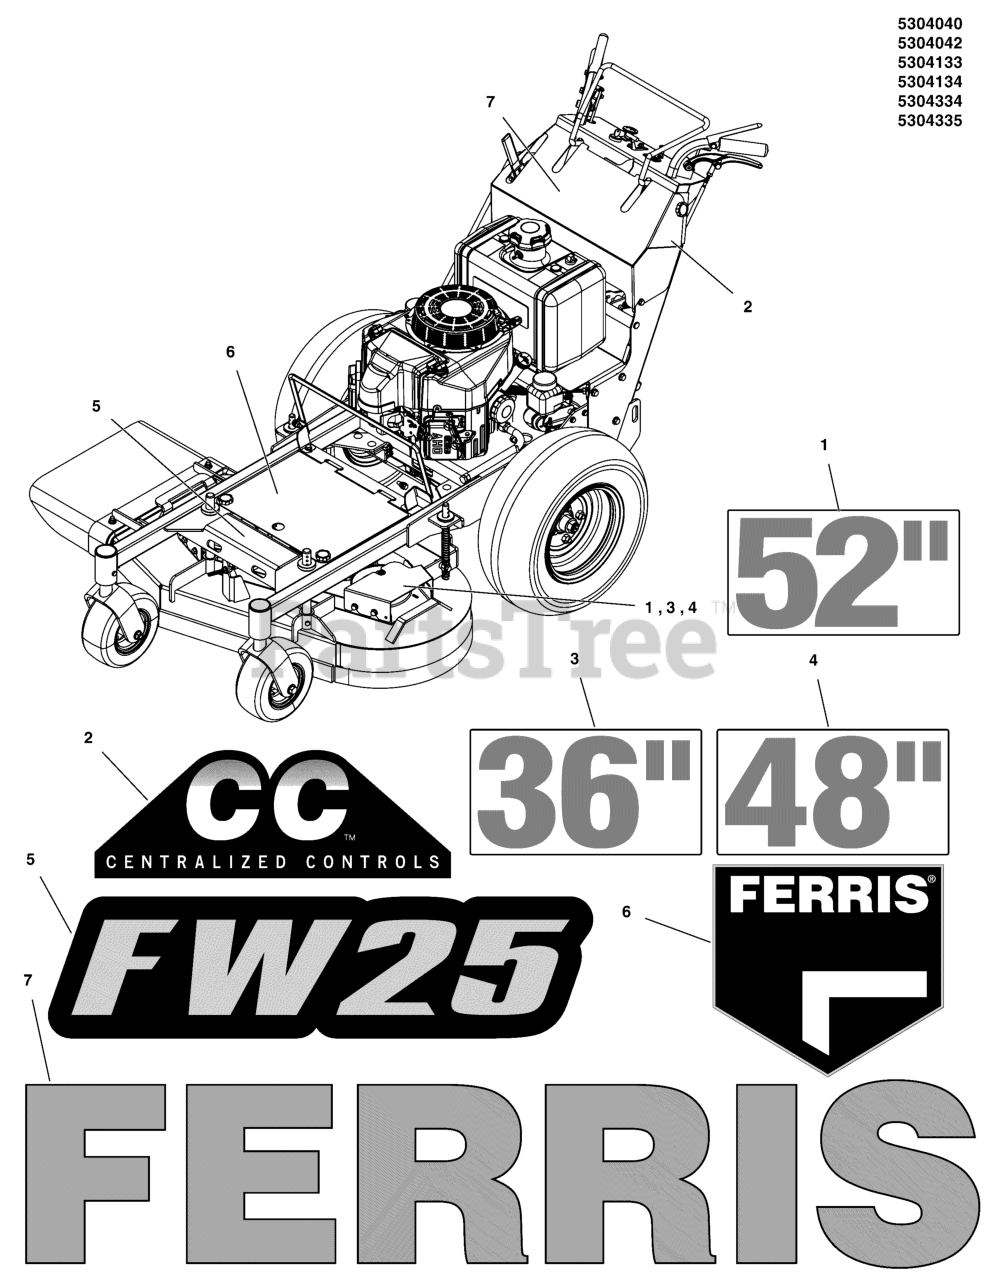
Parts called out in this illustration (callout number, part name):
1	DECAL, 52
2	DECAL, CENTRALIZED CONTROLS
3	DECAL, 36
4	DECAL, 48
5	DECAL, MODEL
6	DECAL, BRAND
7	DECAL, FERRIS, 2.23" X 11.39"
